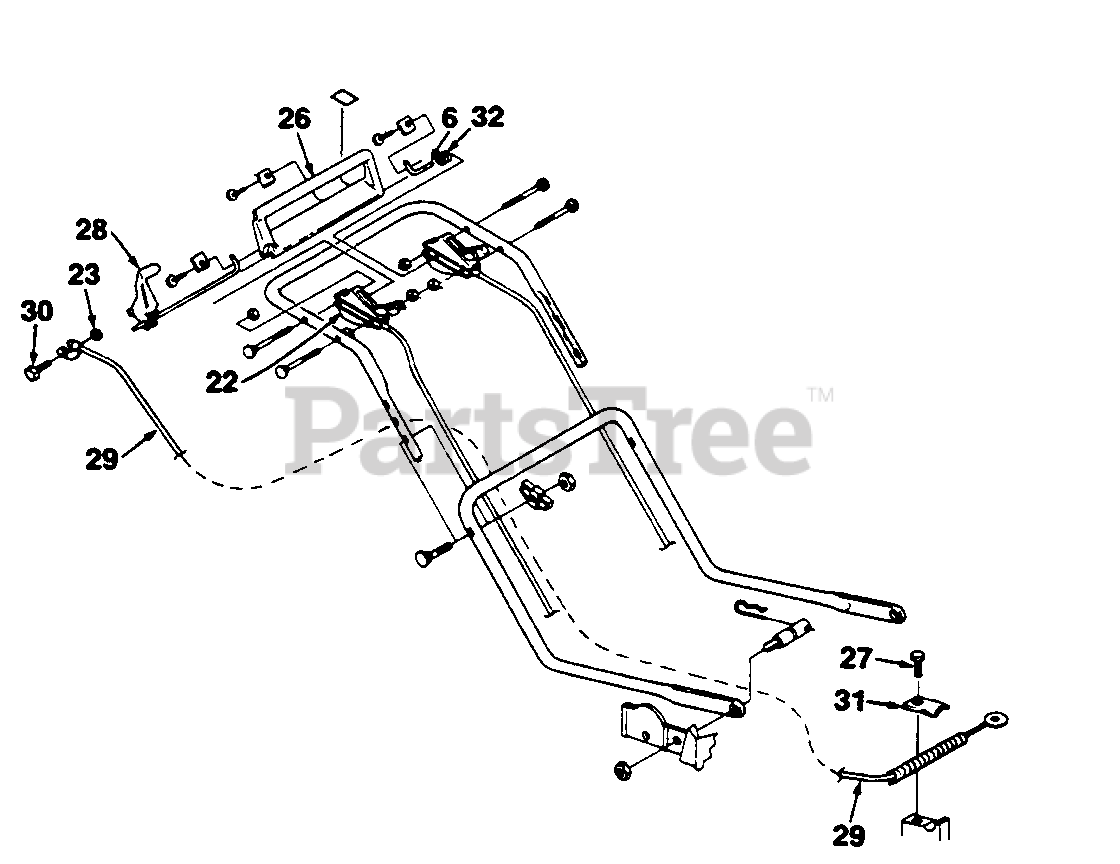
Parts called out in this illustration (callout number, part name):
6	SHAFT - Pivot
22	ENGINE - Control
23	NUT-Lock (1/4-20)
26	BAIL- Brake control
27	SCREW- 1/4-20 x 5/8"
28	TRACTION LEVER ASSY.
29	CONTROL CABLE TBO
30	SCREW - 1/4-20 x 1 1/2"
32	SPRING - Compression
